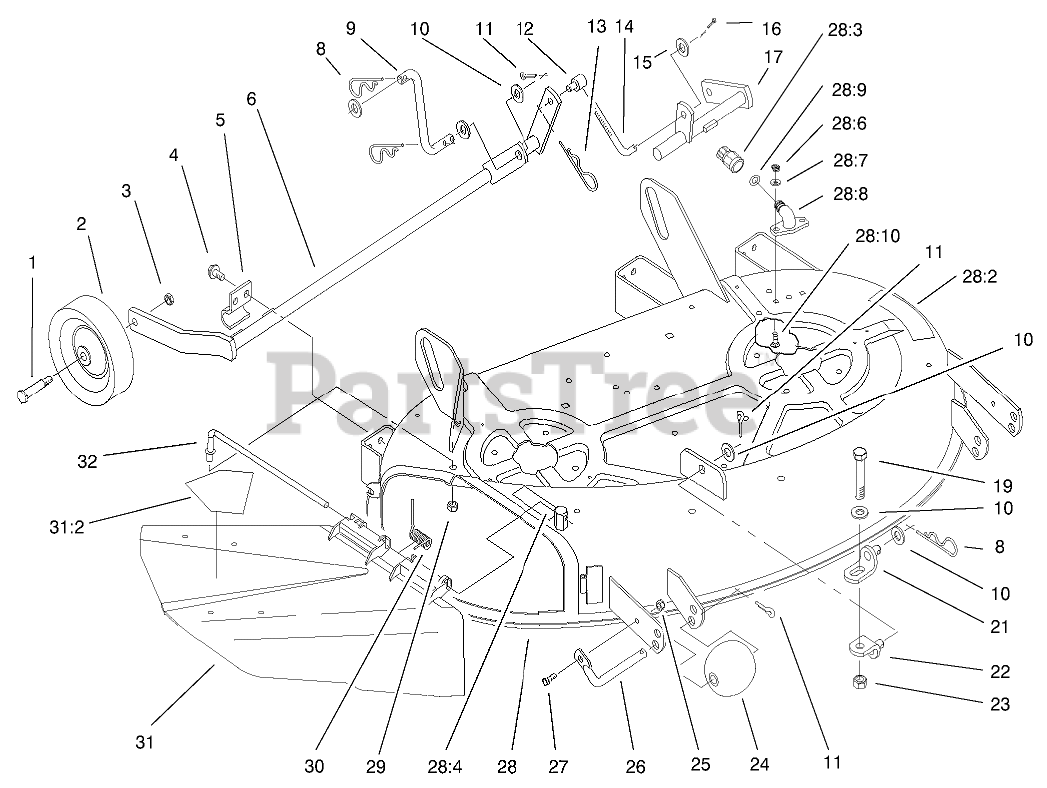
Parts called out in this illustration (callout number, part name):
1	BOLT-SHOULDER
2	WHEEL
3	NUT-HEX
4	SCREW-HWH, TAPTITE
6	SHAFT-RH
8	PIN-COTTER, HAIR
9	LINK-REAR
10	WASHER-FLAT
11	PIN-COTTER
12	TRUNNION
13	PIN-HAIR
14	ROD-LIFT
15	WASHER-FLAT
16	PIN-COTTER
17	SHAFT-LH
19	SCREW-HH
21	BRACKET-LIFT, LOWER
22	BRACKET-LIFT, UPPER
23	NUT-JAM
24	ROLLER
25	NUT-LOCK, NI
26	Shaft-Roller
27	SCREW-HH
28	DECK ASM
28:2	DECAL-DANGER
28:3	CONNECTOR-HOSE
28:4	DECAL-CAUTION
28:6	NUT-LOCK, NI
28:7	WASHER-FLAT
28:8	FITTING-WASHOUT
28:9	O-RING
28:10	BOLT-CARR
29	NUT-LOCK, NI
30	SPRING
31	DEFLECTOR ASM
31:2	DECAL-DANGER
32	ROD-PIVOT
